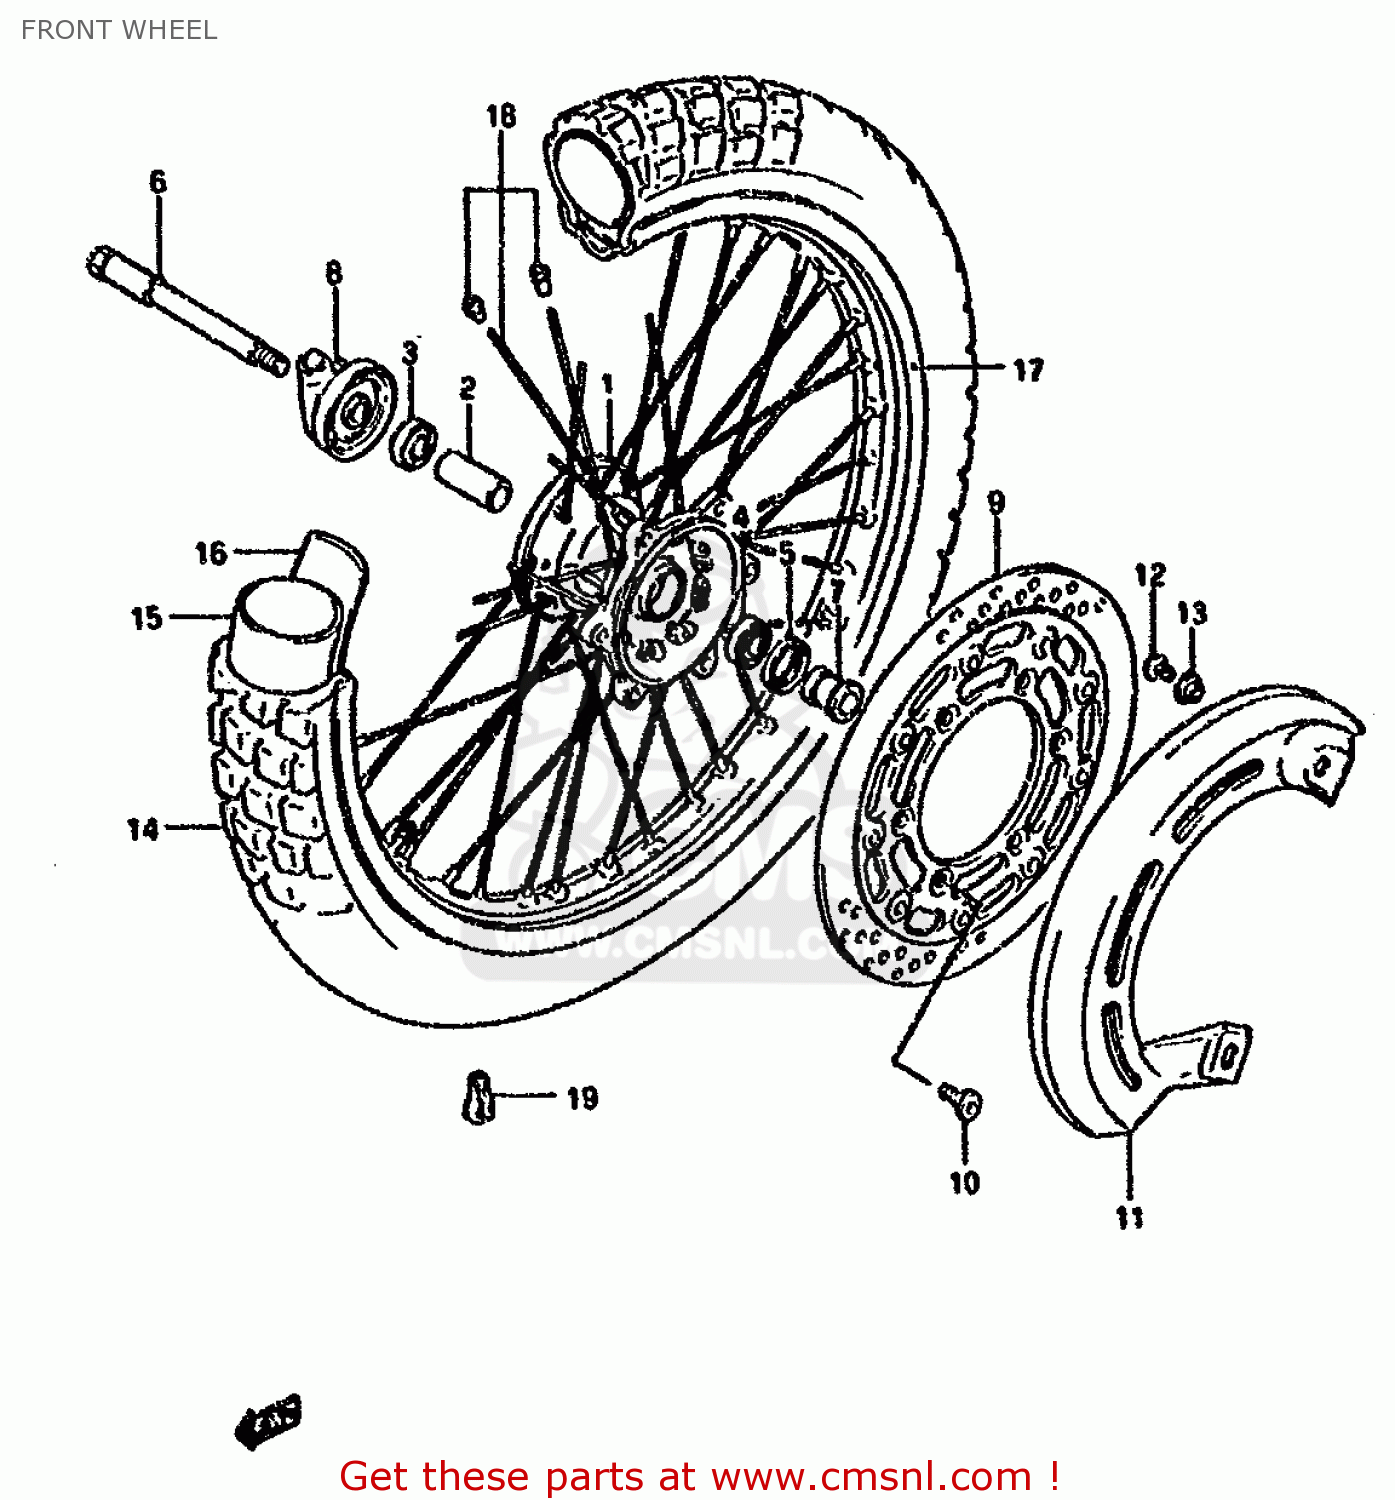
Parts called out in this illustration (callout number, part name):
1	HUB,FR WHEEL
2	SPACER,FR HUB BEARING
3	BEARING
4	BEARING
5	SEAL,OIL(22X35X5)
6	AXLE,FR
7	SPACER,FR AXLE,L
8	BOX ASSY,SPEEDOMETER GEAR
9	DISC,FR BRAKE
10	BOLT,BRAKE DISC
11	COVER,FRONT BRAKE DISC
12	SCREW 6X12
13	WASHER
14	TIRE,90/90-21
15	TUBE
16	PROTECTOR,WHEEL INNER
17	RIM,FR WHEEL(21X1.85)
18	SPOKE SET,FR WHEEL
19	BALANCER,WHEEL
